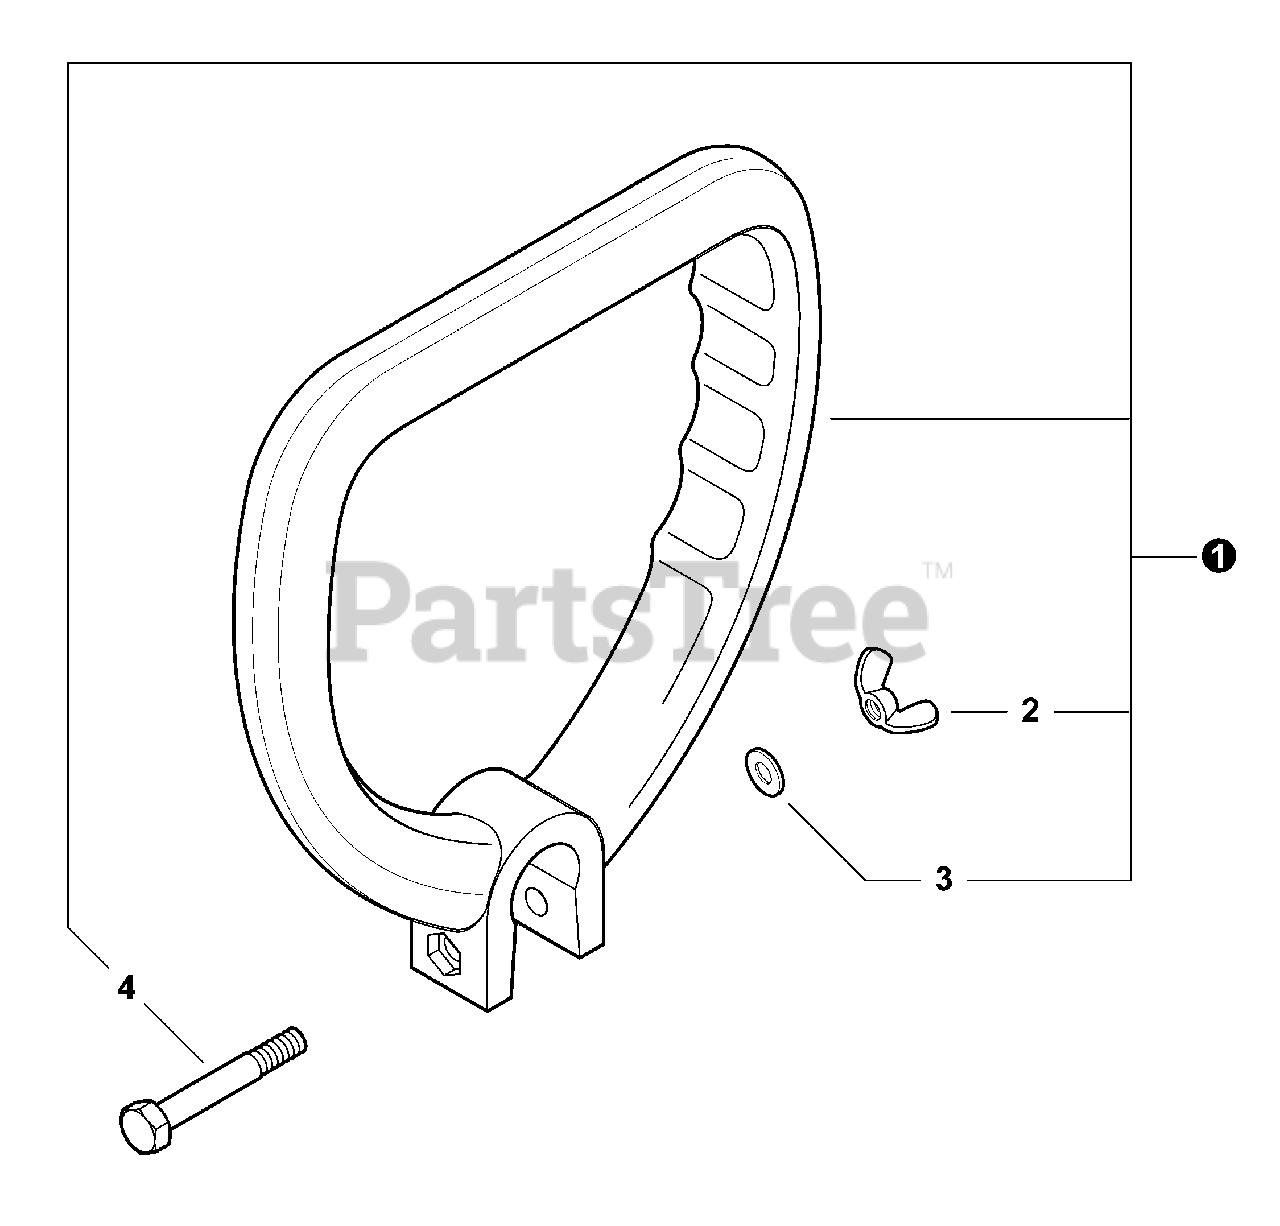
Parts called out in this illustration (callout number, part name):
1	HANDLE ASSY
2	NUT, WING 1/4"-20
3	WASHER, 1/4"
4	BOLT 6×45
